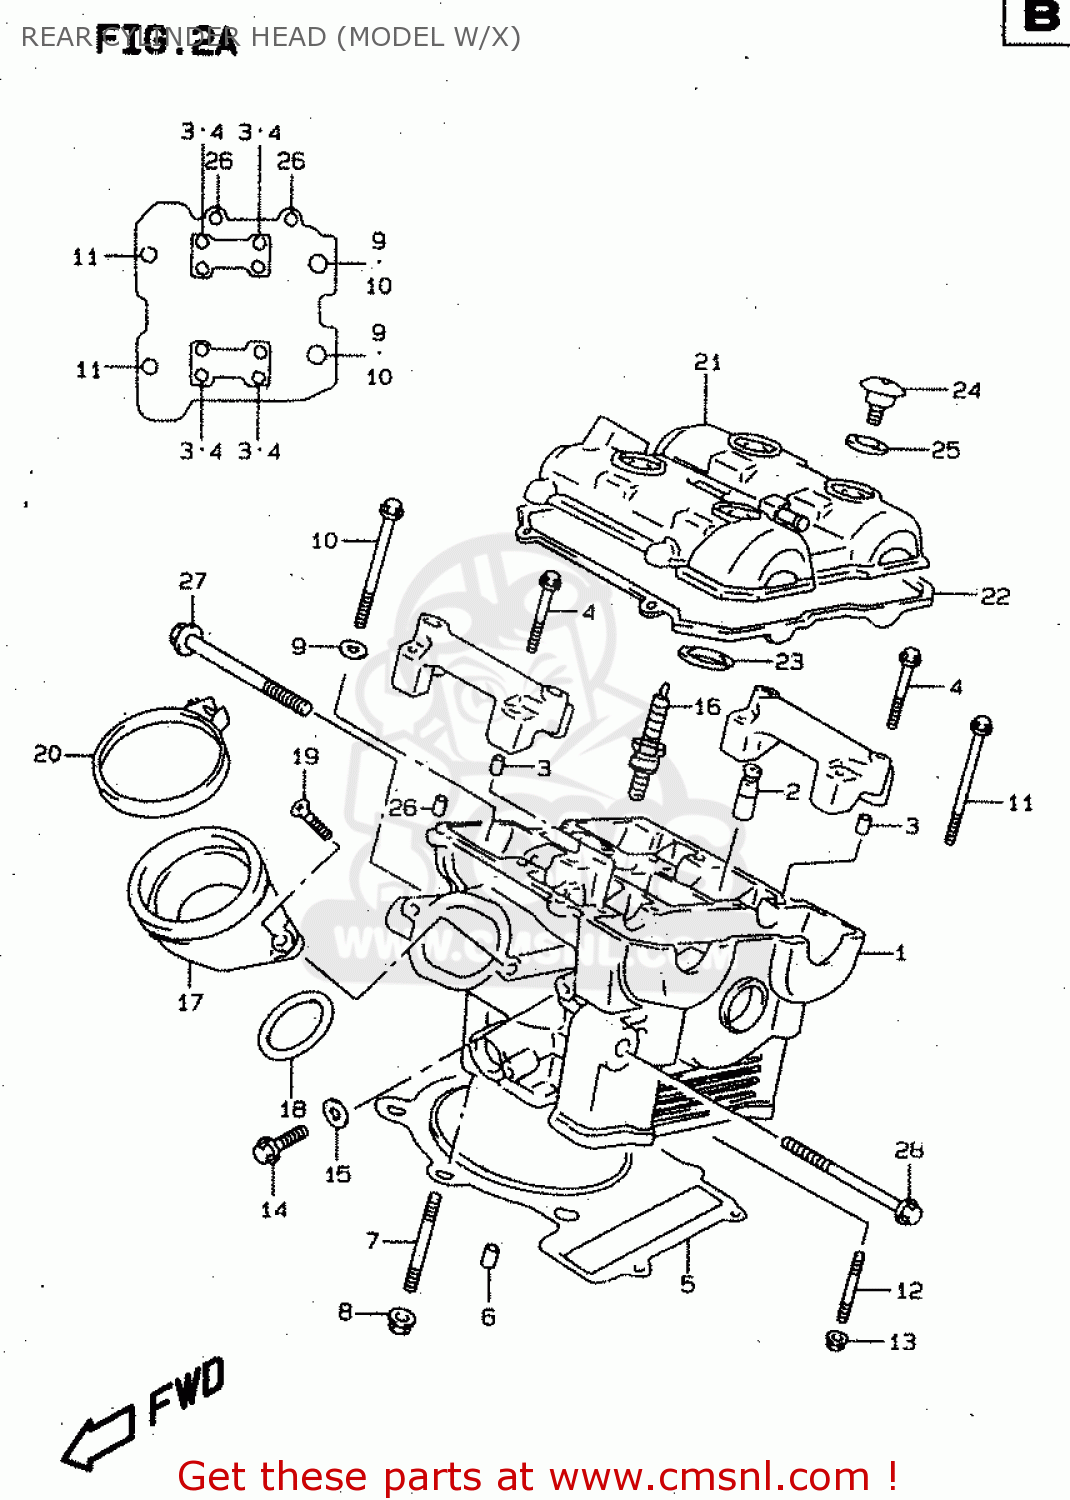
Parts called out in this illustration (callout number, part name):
1	HEAD,CYLINDER
2	GUIDE,VALVE
3	PIN(6.2X8X11)
4	BOLT(6X39)
5	GASKET,CYLINDER HEAD (NAS)
6	PIN
7	BOLT,STUD
8	NUT
9	WASHER(10.5X19X2)
10	BOLT(10X175)
11	BOLT(6X70)
12	BOLT,STUD
13	NUT
14	BOLT
15	GASKET(5.8X13X1.2) (NAS)
16	PLUG,SPARK(CR8EK)
17	PIPE ASSY,INTAKE
18	O RING(D:2.4,ID:55.6)
19	SCREW
20	CLAMP
21	COVER,CYLINDER HEAD RR
22	GASKET,CYL HEAD COVER NO.1 (NAS)
23	GASKET,CYL HEAD COVER NO.2
24	BOLT(7X17.5)
25	WASHER(10.6X25.5X2.3)
26	PIN(6.2X8X11)
27	BOLT
28	BOLT
